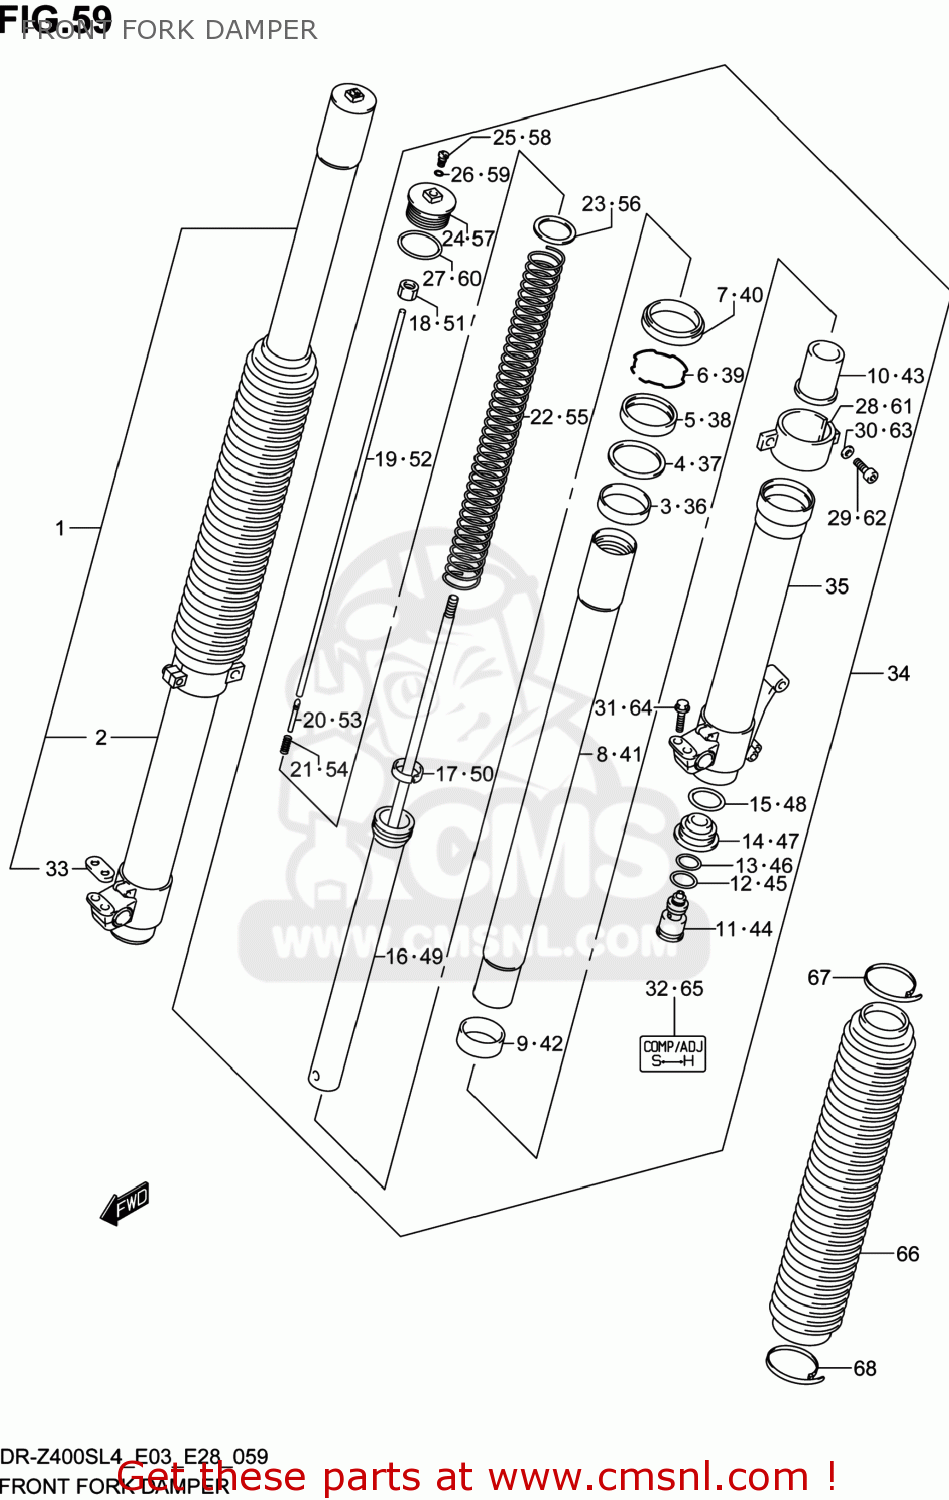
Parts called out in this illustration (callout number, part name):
1	DAMPER ASSY,FR FORK,R
2	TUBE,OUTER,R
3	BUSH,GUIDE
4	SPACER,SEAL
5	SEAL,OIL
6	RING,STOPPER
7	SEAL,DUST
8	TUBE,INNER
9	BUSH,SLIDE
10	PIECE,OIL LOCK
11	BOLT,CTR
12	O RING
13	O RING
14	PLATE,END
15	O RING
16	ROD,FR DAMPER
17	BUSH,SLIDE
18	NUT
19	ROD,PUSH
20	NEEDLE
21	SPRING,PUSH ROD
22	SPRING,FR(K=8.63N/0.88KG)
23	JOINT,SPRING
24	BOLT,FORK
25	BOLT,PLUG
26	O RING,PLUG
27	O RING
28	HOLDER,BOOT
29	BOLT
30	WASHER(5.5X10X1)
31	BOLT,HANDLE HOLDER(8X35)
32	LABEL
33	COVER,AXLE HOLDER
34	DAMPER ASSY,FR FORK,L
35	TUBE,OUTER,L
36	BUSH,GUIDE
37	SPACER,SEAL
38	SEAL,OIL
39	RING,STOPPER
40	SEAL,DUST
41	TUBE,INNER
42	BUSH,SLIDE
43	PIECE,OIL LOCK
44	BOLT,CTR
45	O RING
46	O RING
47	PLATE,END
48	O RING
49	ROD,FR DAMPER
50	BUSH,SLIDE
51	NUT
52	ROD,PUSH
53	NEEDLE
54	SPRING,PUSH ROD
55	SPRING,FR(K=8.63N/0.88KG)
56	JOINT,SPRING
57	BOLT,FORK
58	BOLT,PLUG
59	O RING,PLUG
60	O RING
61	HOLDER,BOOT
62	BOLT
63	WASHER(5.5X10X1)
64	BOLT,HANDLE HOLDER(8X35)
65	LABEL
66	BOOT
67	BAND,BOOT UPR
68	BAND,BOOT LWR
